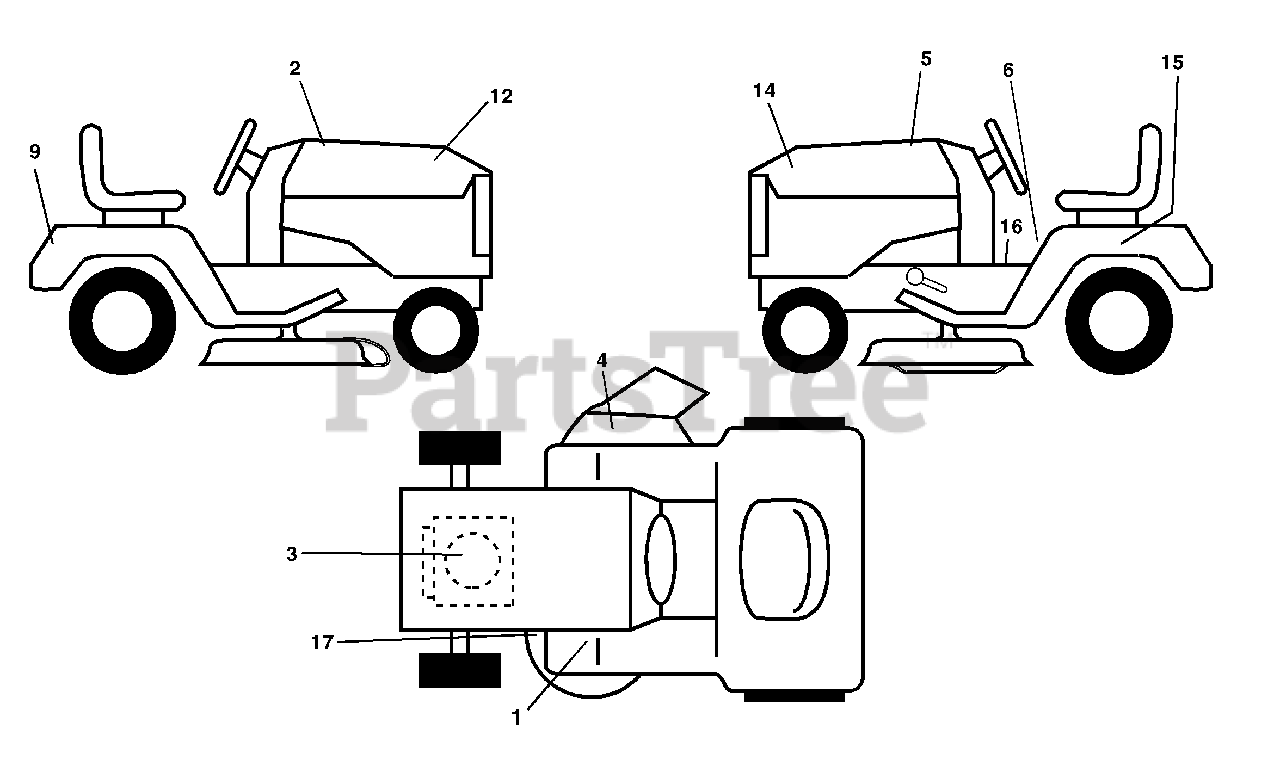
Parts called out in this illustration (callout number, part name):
1	Decal, Clutch/Brake Eng/Fr
2	Decal, Hood Cust. Resp.
3	Decal, Engine HP
4	Decal, Warning
5	Decal, Hood Replc. Parts
6	Decal, Fender Danger English
9	Decal, Fender
12	Decal, Hood RH
14	Decal, Hood LH
15	Decal, Caution, Battery
16	Decal, Oper Sdl P/L Gear Dr Eng
17	Decal, V-Belt Sch.
